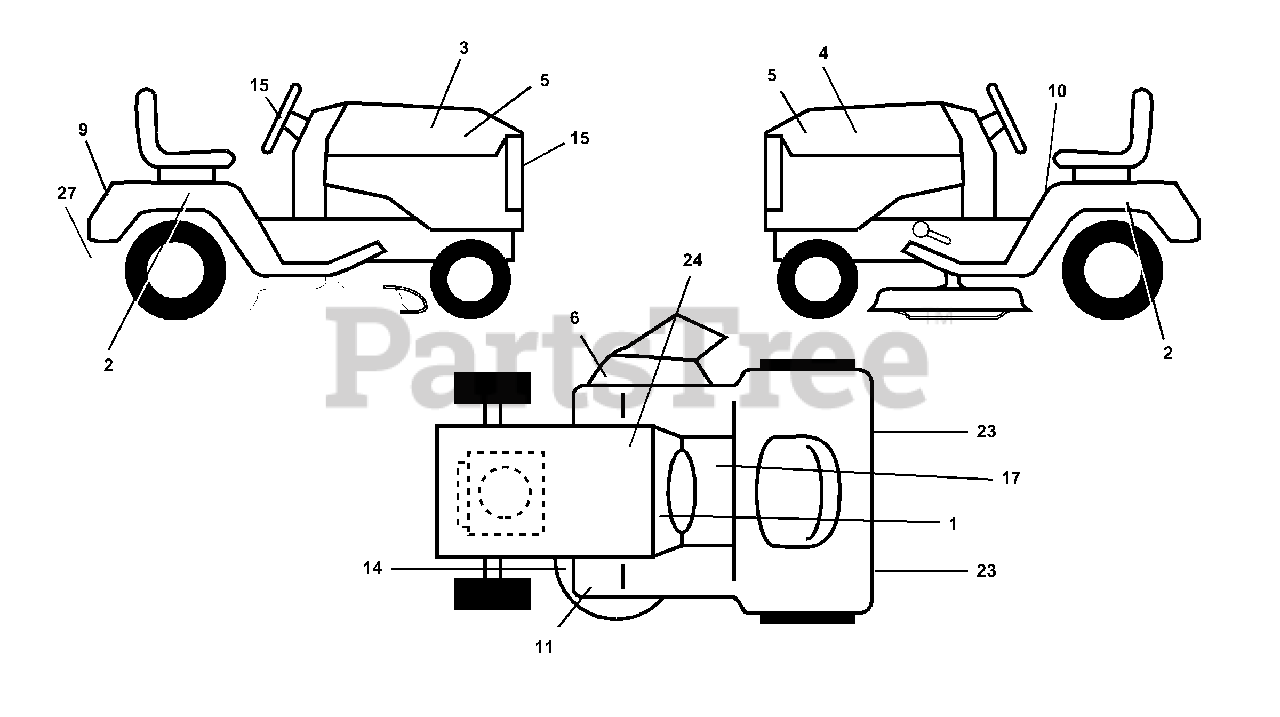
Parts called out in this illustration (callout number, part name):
1	Decal, Operating Instruction
2	Decal, Fender Auto
3	Decal, Hood, RH
4	Decal, Hood, LH
5	Decal, Side Panel
6	Decal, Warning
9	Decal, Fender
10	Decal, Danger
11	Decal, Clutch/Brake
14	Decal, V-Belt Schematic
15	Decal, Ins. Strg Whl
17	Decal, Saddle Brake Parking
23	Reflector, Taillight
24	Decal, Btry Dngr/Psn
27	Decal,Drawbar
